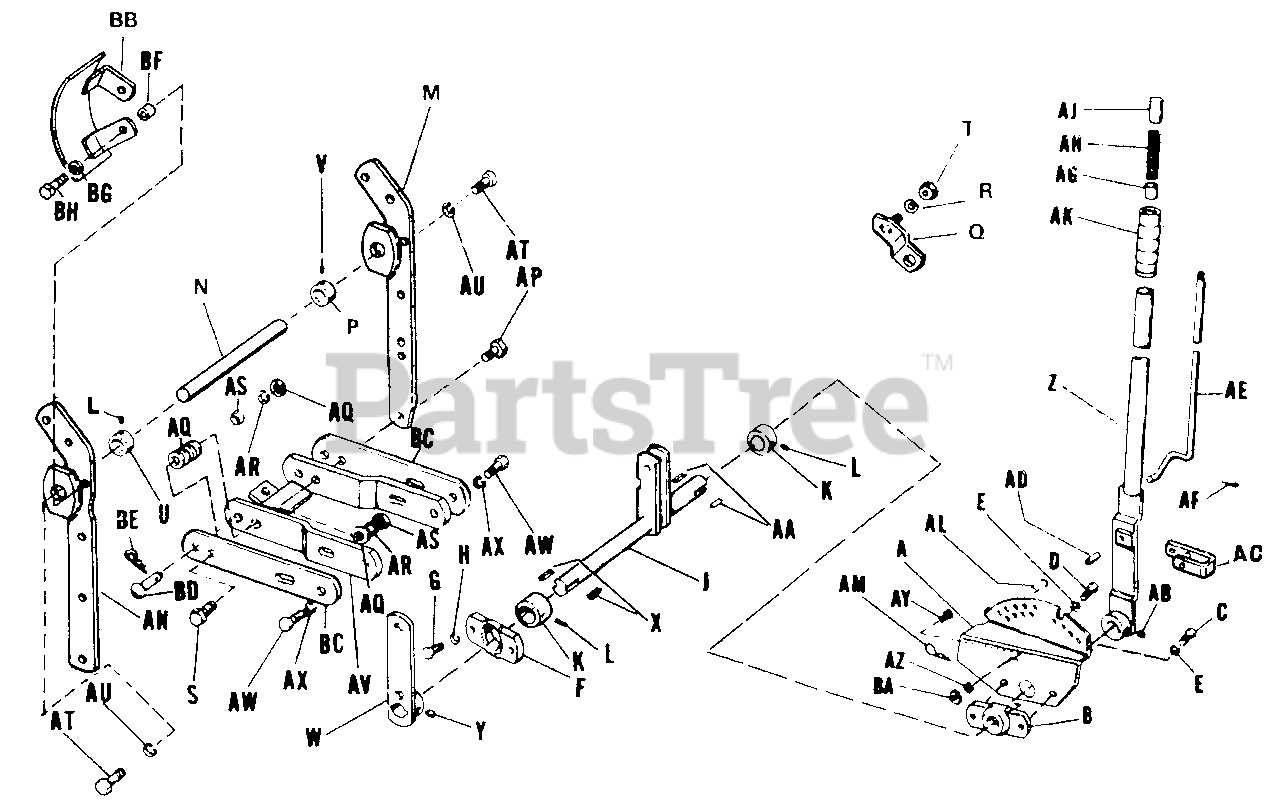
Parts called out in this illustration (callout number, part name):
A	Lift Lever Quadrant
B	Lift Lever Bearing
C	Hex. Cap Screw, 3/8"-16 x 7/8"
D	Hex. Cap Screw, 3/8"-16 x 1 1/4"
E	Lock Washer, 3/8"
F	Lift Lever Bearing
G	Hex. Cap Screw, 3/8"-16 x 7/8"
H	Lock Washer, 3/8"
J	Lift Shaft Assembly
K	Set Collar
L	Set Screw, 5/16"-18 x 5/16"
M	Arm Assembly
Q	Pivot Bar Assembly
R	Plain Washer, 3/8"
S	Hex. Cap Screw, 7/16"-14 x 1 3/4"
T	Hex. Nut, 3/8"-16
U	Set Collar
V	Set Screw, 5/16"-18 x 1/2"
W	Front Lift Lever Assembly
Y	Set Screw, 5/16"-18 x 1/4"
Z	Lift Lever Assembly
AB	Set Screw, 5/16"-18 x 1/4"
AC	Lift Lever Latch
AE	Latch Rod
AF	Cotter Pin, 8/32" x 3/4"
AJ	Thumb Button
AK	Handle Grip
AM	Spring Clip
AN	Arm Assembly
AP	Hex. Cap Screw 7/16"-14 x 1 1/2"
AQ	Plain Washer, 3/8"
AR	Lock Washer
AS	Full Hex. Nut, 7/16"
AT	Hex. Cap Screw, 7/16"-14 x 1"
AU	Lock Washer, 7/16"
AV	Draw Bar Assembly
AW	Hex. Cap Screw, 7/16"-14 x 1 1/4"
AX	Lock Washer, 7/16"
AY	Hex. Cap Screw, 1/4"-20 x 5/8"
AZ	Lock Washer, 1/4"
BA	Hex Nut, 1/4-20
BB	Pulley Guard Assembly
BD	Round Head Pin
BE	Spring Clip
BG	Lock Washer, 7/16"
BH	Hex. Cap Screw, 7/16"-14 x 1 1/2"
